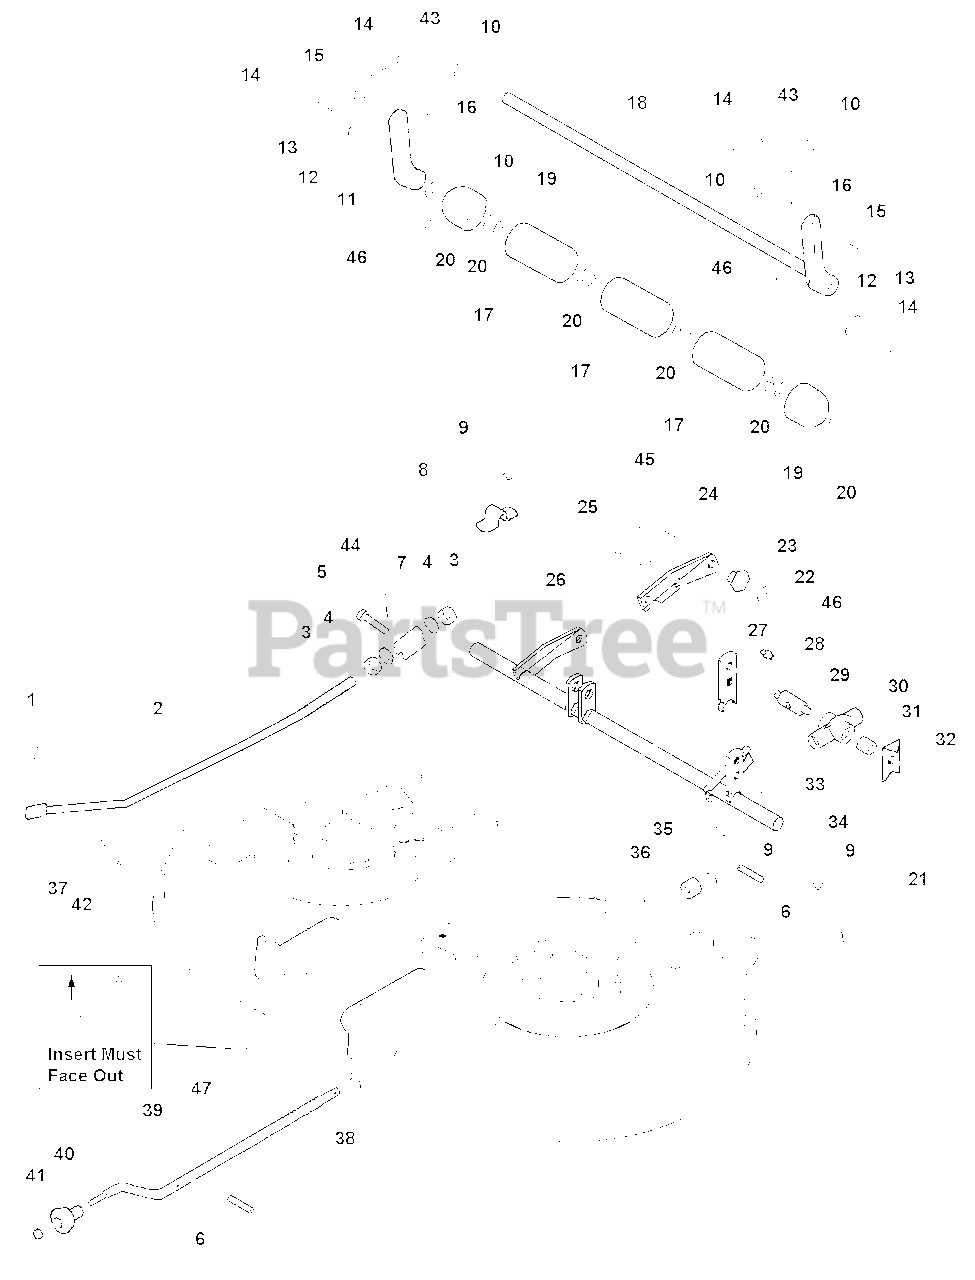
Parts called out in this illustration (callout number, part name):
1	CAPSCREW, Hex Head, 3/8-16 x 1-3/4
2	ROD & STRAP ASSEMBLY
3	NUT, Hex, 5/8-11, Black
4	WASHER, 5/8
5	PIN, Round Head, Drilled, 3/8 x 2, Black
6	PIN, Spring
7	TRUNNION
8	STRAP
9	CAPSCREW, Hex Washer Head, Tap Tite, 5/16-18 x 3/4, Black
10	NUT, Hex Flange Lock, 3/8-16, Black
11	BAR, Roller
13	WASHER, 5/16, Black
14	CAPSCREW, Hex Head, 3/8-16 x 1-1/2, Black
15	CAPSCREW, Hex Head, 5/16-18 x 1-1/4, Black
16	CHAIN, Link, 5-5/8 Long, 4 Links
17	ROLLER, 5/8 ID x 2-1/2 OD x 4 Long
18	SHAFT & BAR ASSEMBLY
19	ROLLER, 5/8 ID x 2-1/2 OD x 2 Long
20	WASHER, 5/8
21	PLATE, Indicator
22	WASHER, 5/16, Black
23	CAM, Eccentric
25	CARRIAGE BOLT, 1/2-13 x 2-1/2, Black
26	SHAFT ASSEMBLY, Rocker
28	FITTING, Lube
32	POINTER, Height of Cut
33	LOCKWASHER, 1/2, Black
34	NUT, Hex, 1/2-13, Black
35	WASHER, Special, Nylon
36	BEARING, Thrust
38	WASHER, 5/8, Black
39	CRANK, Height of Cut
40	KNOB, Spinner
41	NUT, Push, 3/8
42	WASHER, 3/8, Black
43	WASHER, 3/8
44	PIN, Cotter
45	CARRIAGE BOLT, 5/16-18 x 1-1/4
46	NUT, Hex Lock, 3/8-16
47	NUT, Hex Lock, Aluminum Insert, 3/8-16
